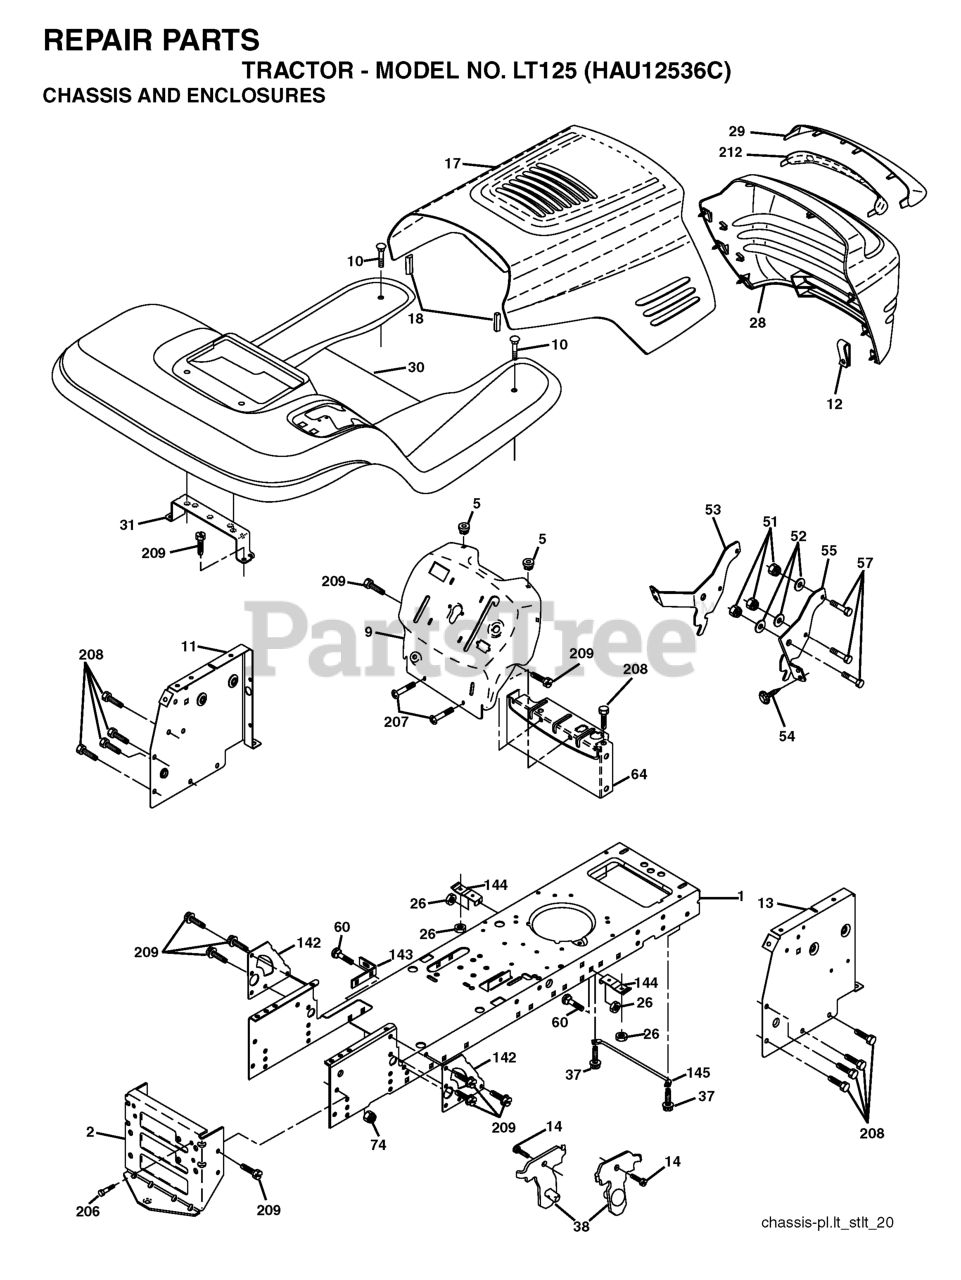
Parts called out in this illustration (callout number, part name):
1	CHASSIS STAMPING
2	DRAWBAR, 12GA
5	BUMPER.RUBBER.HOOD
9	DASH
10	BOLT D
11	PANEL.DASH.LH.LTX
13	PANEL DASH RH
17	HOOD ASM.
18	BUMPER.HOOD.LARGE.1.75"
26	NUT
28	GRILLE/LENS ASM
29	LENS
30	FENDER FOOTREST
31	BRACKET.SUPPORT.FENDER
37	Screw 5/16-18 x 1/2 Hex, Self Tapping 5/16-18 x 1/2
38	BRACKET.ASM.PIVOT.MOWER.REAR
51	LOCKNUT.NYLOC.1/4-20
53	BRACKET.GRILLE.LH
54	SCREW.HEX.WS.HD.8-18 X 7/8
57	BOLT
60	Bolt - Rd. Hd. Sq. Neckiage 3/8 16 x 3/4
64	DASH LOWER
142	PLATE REINFORCEMENT
143	BRACKET, SWAYBAR CHASSIS
144	BRKT, FOOT REST
145	ROD PIVOT CHASSIS/HOOD
206	SHOULDER BOLT 5/16-18TT
207	SCREW, 5/16-18 X 1/2
208	SCREW 3/8-16X1/2
209	SCREW, 3/8-16X3/4
212	REPL BY 532 1745-03
